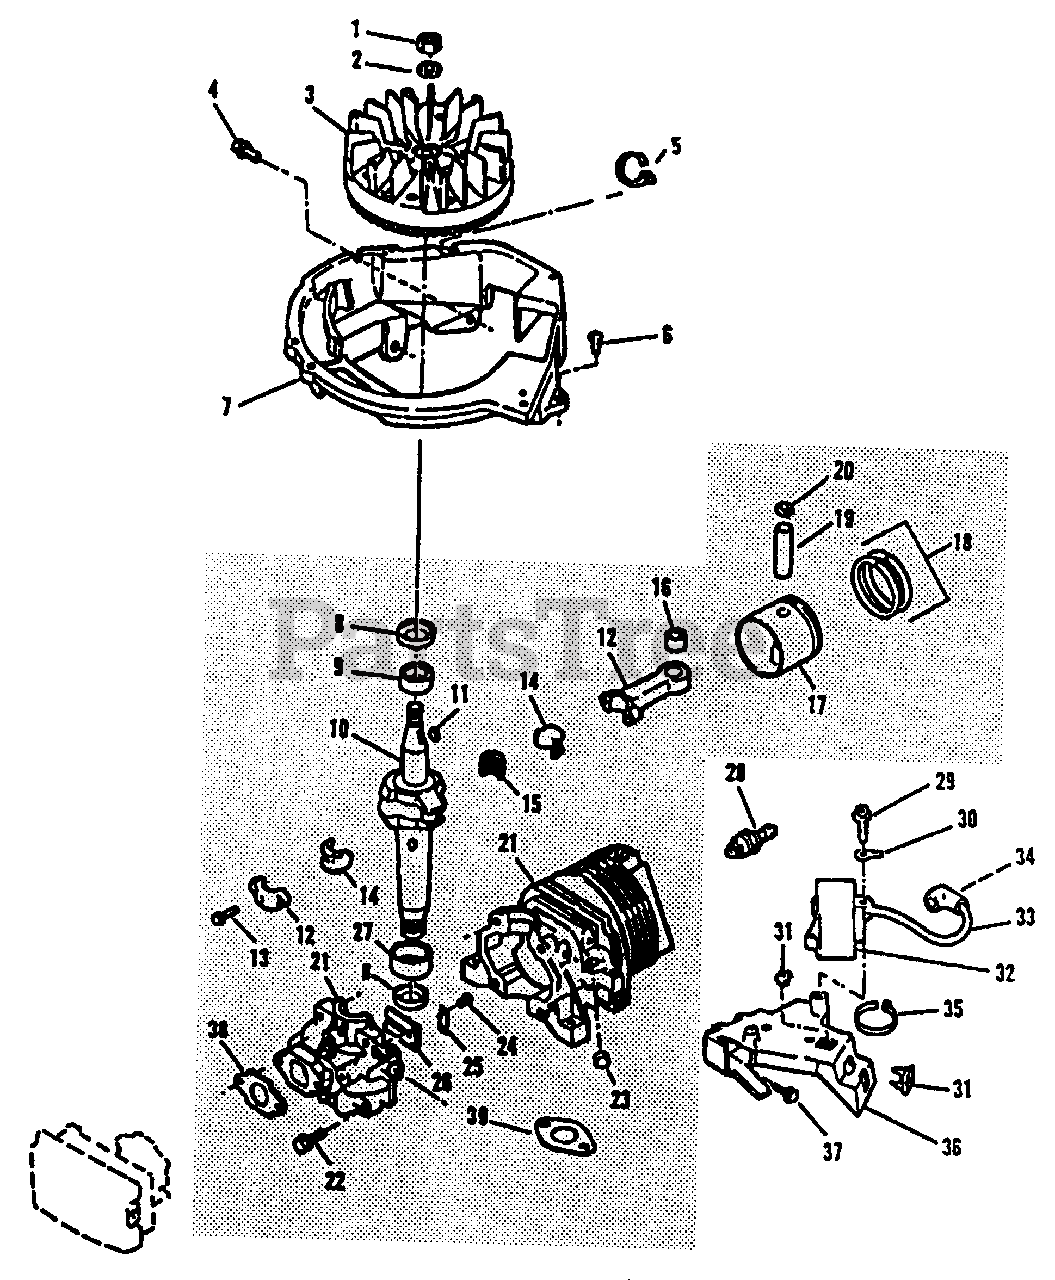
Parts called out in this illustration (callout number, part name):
1	Nut-Flywheel
2	Lockwasher
3	Flywheel
4	Screw
5	Tie Strap
6	Screw-Shd. Base to C.D. Brkt.
7	Base-Shroud
8	Oil Seal
9	Bearing-Upper
10	Crankshaft
11	Key-Flywheel
12	Connecting Rod Assembly
13	Screw-Cap
14	Liner Split
15	Needle Bearing Set
16	Bearing Assembly
17	Piston and Ring Set
18	Ring Set
19	Wrist Pin
20	Retaining Ring
21	Cylinder & Crankcase Cover Assy.
22	Screw-Cover to Crankcase
23	Plug
24	Screw-Reed to Crankcase Cover
25	Plate-Reed Hold Down
26	Reed
27	Bearing-Lower
28	Spark Plug
29	Screw-C.D. Mounting
30	Terminal-Ground Lead
31	Grommet-C.D. Bracket
32	C.D. Ignition Module & Lead Asy.
33	High Tension Lead & Cvr. Asy.
34	Spring Terminal
35	Tie Strap
36	Bracket-Ignition Mounting
37	Screw
38	Gasket-Carb. to Crankcase Cover
39	Exhaust Gasket
